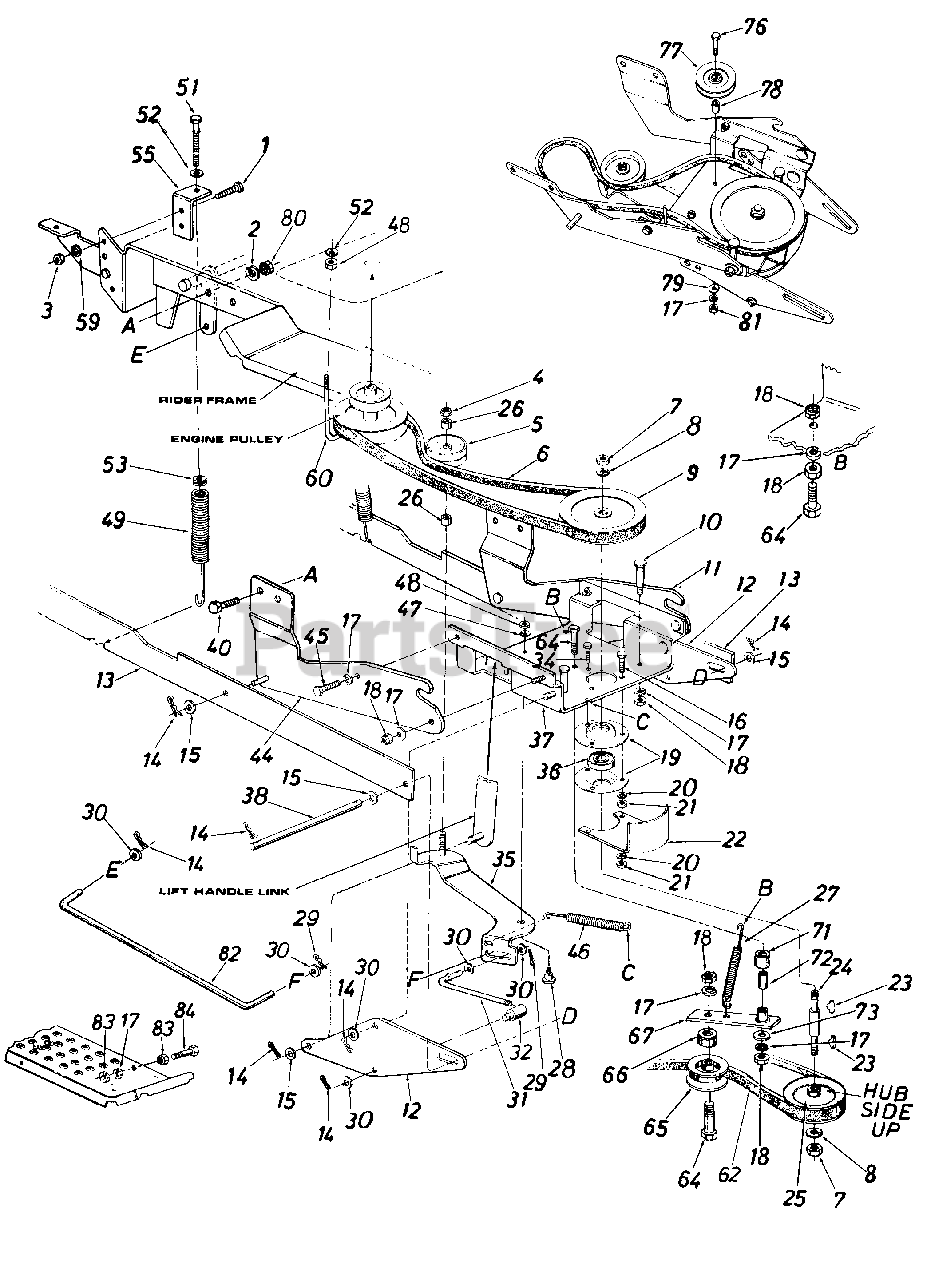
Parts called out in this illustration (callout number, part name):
1	Hex Bolt 1/4-28 x 1.00" Lg. Grade 5
2	L.-Wash. 1/4" I.D.*
3	Hex Nut 1/4-28 Thd.*
4	Hex Cent. L-Nut 3/8-16 0 Thd.
5	Idler Pulley
6	"V"Belt
7	Hex Jam Nut 5/8-11 0 Thd.
8	L.-Wash. 5/8" I.D.*
9	6.50" O.D. x 5/8 Pulley
10	Shoulder Bolt
11	Channel Support Brkt.-R.H.
12	Linkage Brkt.
13	Linkage Arm Ass'y.
14	Intern. Cotter Pin .50 Dia.*
16	Hex Bolt 5/16 x 1.25" Lg.
17	L.-Wash. 3/8" I.D.*
18	Hex Jam Nut 3/8-16 Thd.
19	Bearing Housing
20	L.-Wash. 5/16" I.D.*
21	Hex Nut 5/16-18 Thd.*
24	Pulley Spindle
25	5/8 Pulley-6.28 I.D. x 5.56 0 O.D.
26	Spacer .383 I.D. x .503 0 O.D. x .562 Lg.
27	Extension Spring .54 O.D. x 5.25"
28	Shoulder Bolt
29	Cotter Pin 3/32" Dia.
31	Control Rod
32	Ferrule
34	Hex Sems Scr. 5116-18 x .75" Lg.*
35	Clutch Idler Brkt. Ass'y.
36	Ball Bearing
37	Channel Ass'y.
38	Lift Handle Shaft
40	Hex Self-Tap Scr. 1/4-20 x .75" Lg.
44	Channel Supporting Brkt. L. H.
45	Hex Bolt 3/8-16 x 1.0" Lg.*
46	Extension spring
47	L.-Wash. 5/16" I.D.
48	Hex Nut 5/16-18 Thd.*
49	Helper Spring
51	Hex Scr. 5/16-18 x 2.0" Lg. Special
52	Bell Wash. .345 I.D. x .88 0 O.D. x .06
53	Spring Insert
60	J.-Bolt 5/16-18 Thd.
62	"V"Belt 1/2 "A" x .89" Lg.
64	Hex Bolt 3/8-16 x 2.0" Lg.*
65	Idler Pulley
66	Spacer .385 I.D. x .503 0 O.D. x .562" Lg.
67	Idler Arm Ass'y.
71	Spacer.380" I.D.
72	Spacer .3775 I.D. x .60 0 O.D. x 8.3 Lg.
73	Fl.-Wash. 3/8 I.D. x 1" O.D.' x 1.27
76	Hex Bolt 3/8-16 x 2.5" 4. (Grade 5) 6
77	Idler Pulley .38 I.D. x 3.06 O.D.
78	Spacer .385 I.D. x .630 O.D. x .76 Lg.
79	Fl.-Wash. .39 I.D. x 1-3/4 O.D. x 3/16"
80	Hex L-Nut 1/4-20 Thd.
81	Hex Nut 3/8-16 Thd.*
82	Clutch Control Rod
83	Hex Nut 3/8-24 Thd.*
84	Hex Bolt 3/8-24 x 2.25" Lg.*
